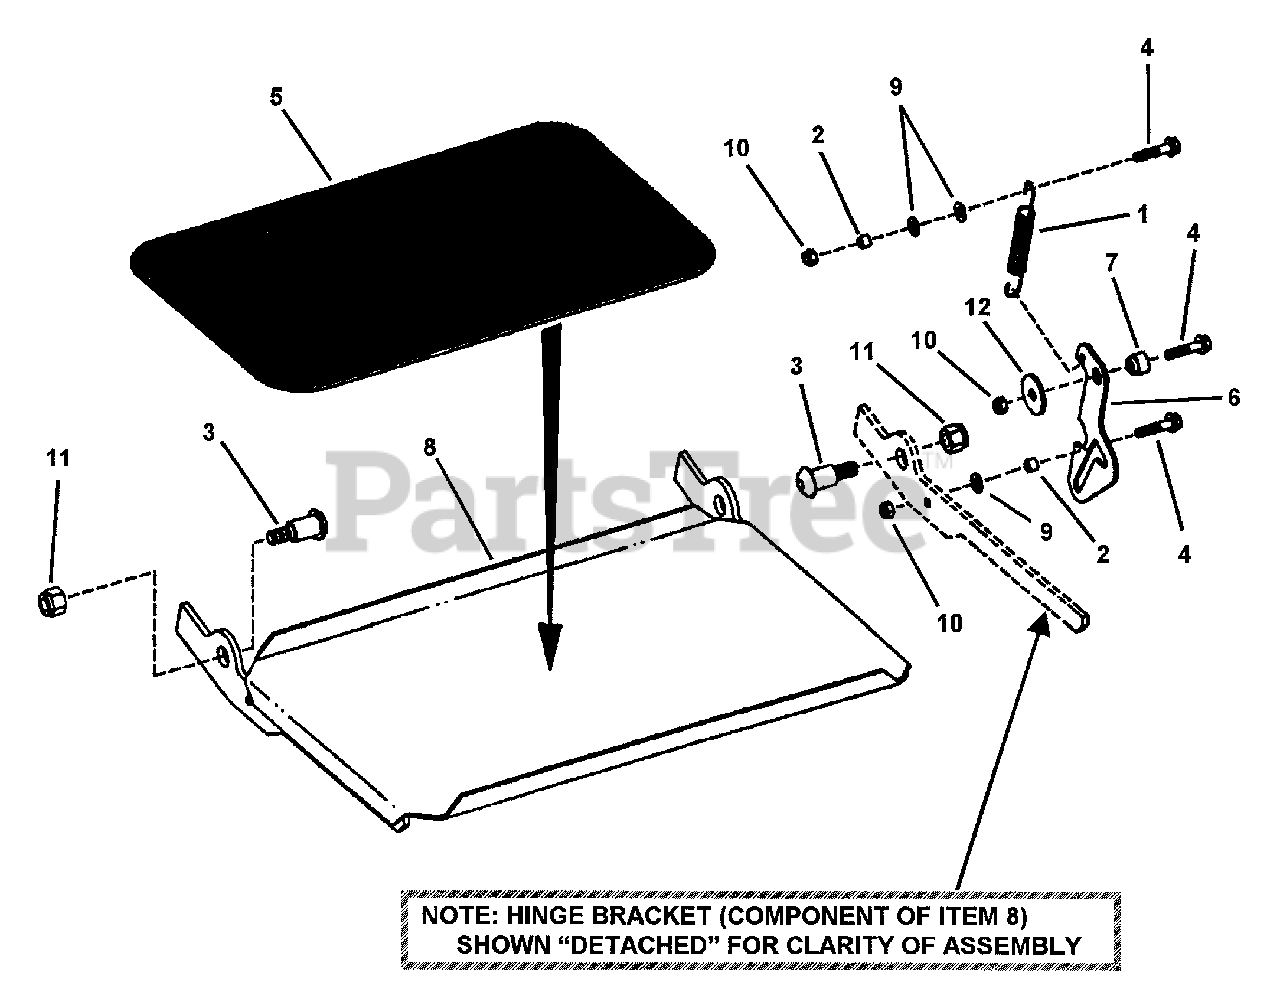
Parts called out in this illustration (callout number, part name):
1	SPRING
2	BUSHING, 5/16 I.D. x 7/16 O.D. x 3/16"
3	BOLT, 1/2-13, 3/4 Dia. X 1-1/16 Shoulder
4	BOLT, 5/16-18 x 1-1/2 Hex Flange Lock, Grade 5
5	FOOT PAD, Rubber
6	PLATE, Footrest Latch
7	SPACER, Shoulder (Latch)
8	FOOTREST (Weldment)
9	WASHER, 11/32 I.D. x 11/16 O.D. x 1/16" Flat
10	NUT, 5/16-18 HEX NYLON LOCK
11	NUT, 1/2-13 HEX SIDE LOCK
12	WASHER, 13/32 I.D. x 1-1/2 O.D. x 1/8" Flat
